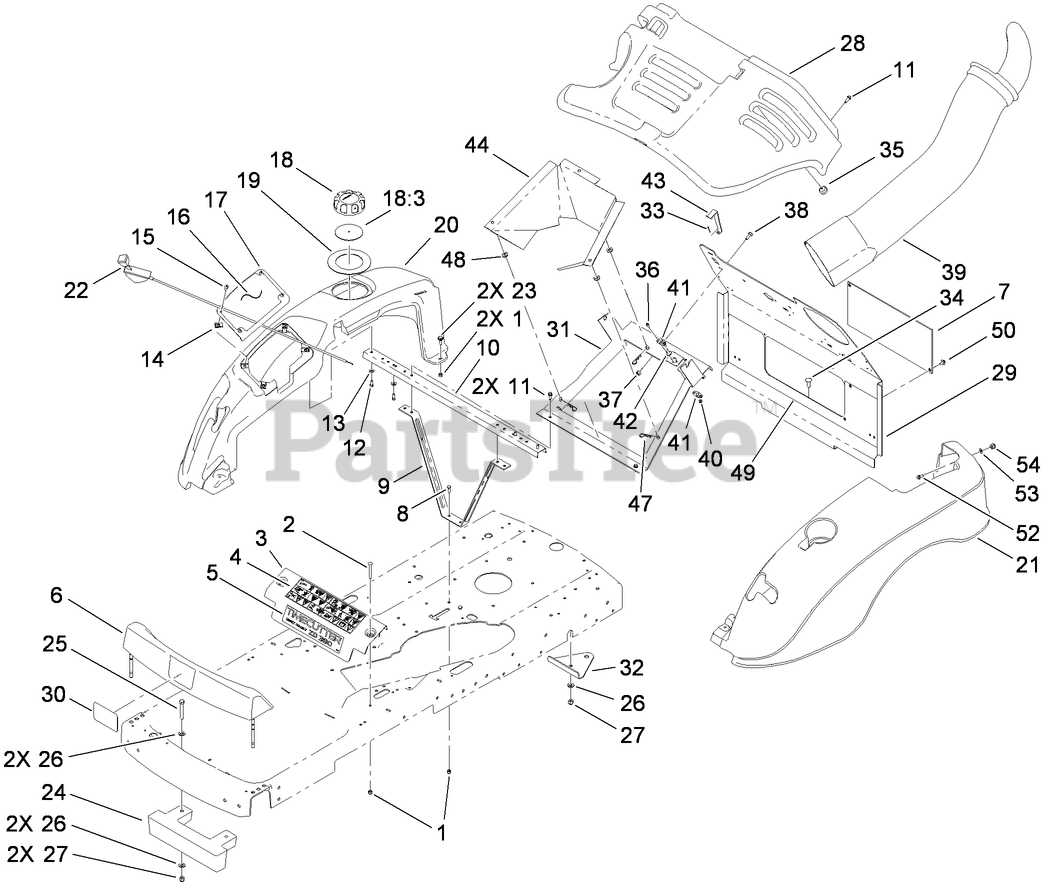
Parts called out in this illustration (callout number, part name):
1	NUT-LOCK, NI
2	SCREW-CARR
3	BRACKET-SUPPORT, FRONT
4	DECAL-DANGER
6	FOOTREST ASM
7	ACCESS DOOR ASM
8	SCREW-HH
9	BRACE ASM
10	CHANNEL-CROSS
11	SCREW-HWH, THREAD ROLL
12	SCREW-PLASTITE
13	WASHER-FLAT
15	SCREW-PRH
16	DECAL-CONTROL
17	PANEL-CONTROL
18	GAS CAP ASM
18:3	GASKET-CAP, GAS
19	SEAL-RUBBER
20	COVER-SIDE, RH
21	COVER-SIDE,LH
22	CABLE-THROTTLE
23	SCREW-SHOULDER
24	WEIGHT-BAGGER
25	SCREW-HH
26	WASHER-FLAT
27	NUT-LOCK, NI
28	COVER-ENGINE
29	SHIELD-HEAT, BAG
31	OFFSET HINGE ASM
32	HITCH-TRAILER
33	PIN-COTTER
34	SCREW-CARR
35	GROMMET
36	SCREW-HSBH
37	NUT-LOCK, NI
38	SCREW-HH
39	TUBE-DISCHARGE
40	NUT-LOCK, NI
42	PIN-HOOD
43	TAB-SWITCH
44	DUCT-ENGINE FAN
47	PIN-HAIR
48	WASHER-RUBBER
49	FOIL-HEAT SHIELD, BAG
50	SCREW-HHFTF
52	SCREW-HHF
53	WASHER-FLAT
54	NUT-LOCK, NI
